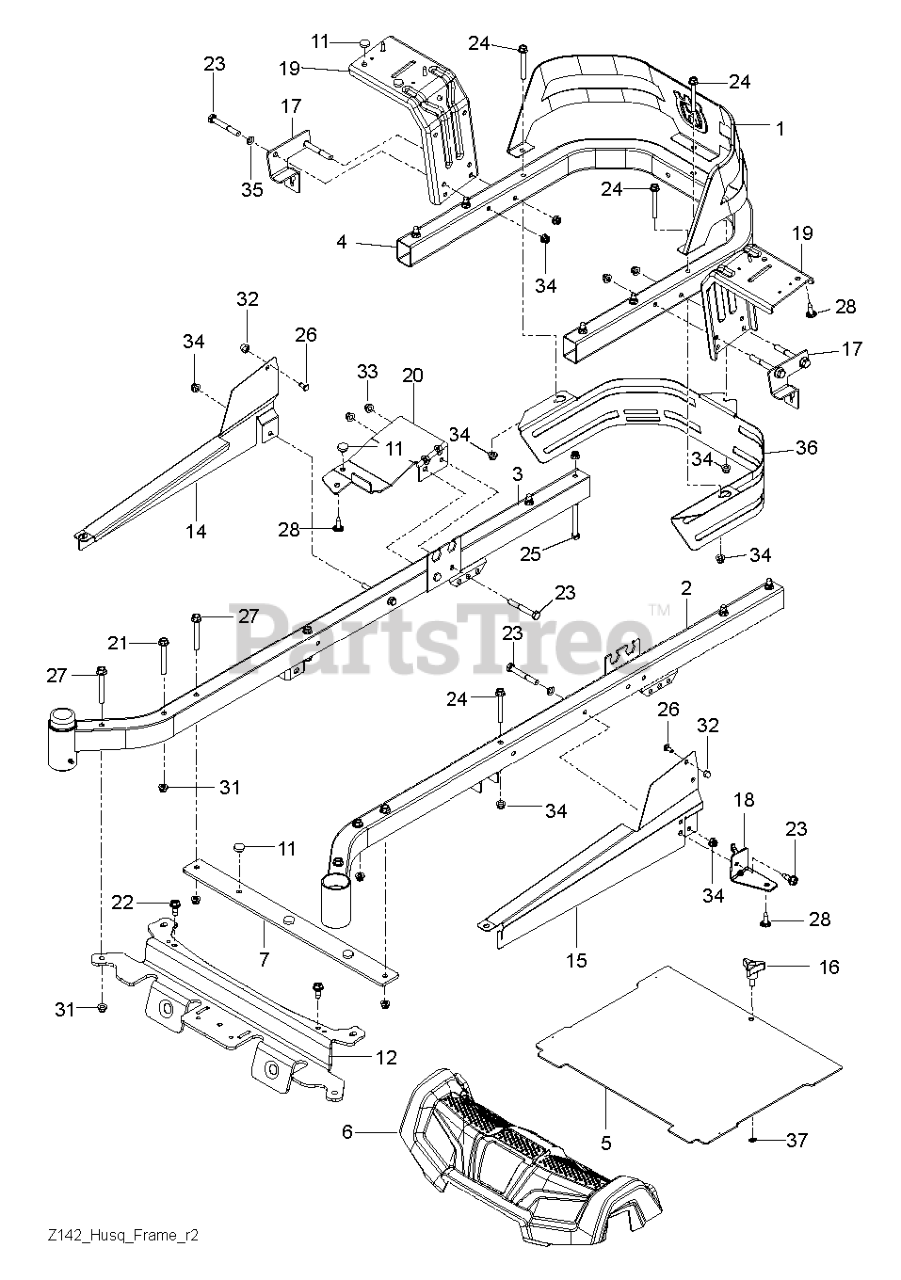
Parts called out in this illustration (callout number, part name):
1	GUARD.ENGINE.HUSQ.RZ.X498
2	FRAME.TUBE.RZ.MAIN.WELD.RH.ORG
3	FRAME.TUBE.RZ.MAIN.WELD.LH.ORG
4	TUBE.PNT.FRAME.RER.HUSQ.23".RZ
5	PLATE FOOT ORANGE X668
6	COVER.FOOTREST.REFRESH.ASM
7	FOOTREST.PLATE.SUPPORT.X431
11	GROMMET.BUMPER
12	CROSS.PNT.MEMBER.BLK
14	COVER.RAIL.RH.RZ.X668
15	COVER.RAIL.LH.RZ.X668
16	KNOB W/STUD
17	BRKT ROD.BYPASS.EZT.X431
18	SUPPORT.PNT.LH.CONSOLE.FRONT
19	FENDER.SUPPORT.PNT.X431
20	SUPPORT.PNT.RH.CONSOLE.FRONT
21	BOLT SHOULDER,FLANGED,3/8-16X3
22	BOLT.5/16-18.THRD.ROLL.SHOULDR
23	BOLT.FIN HEX 5/16-18UNC X2 1/4
24	BOLT HEX
25	BOLT.HEX.FIN.3/8-16 X 3.GR5
26	BOLT.CARRIAGE.5/16-18.7/16
27	HHFS 3/8-16 X 3 GRD 5 ZD
28	SCREW.#10 X 0.750.BOS
31	NUT 3/8-16 HEX FLG NYLOC ZD
32	NUT ACORN,FLANGED,5/16-18
33	NUT LOCK HEX FLANGE 5/16-18
34	5/16-18 NYLOC FLANGE NUT
35	WASHER
36	GUARD REAR MUFFLER GUARD, Z200
37	WASHER 5/16"
